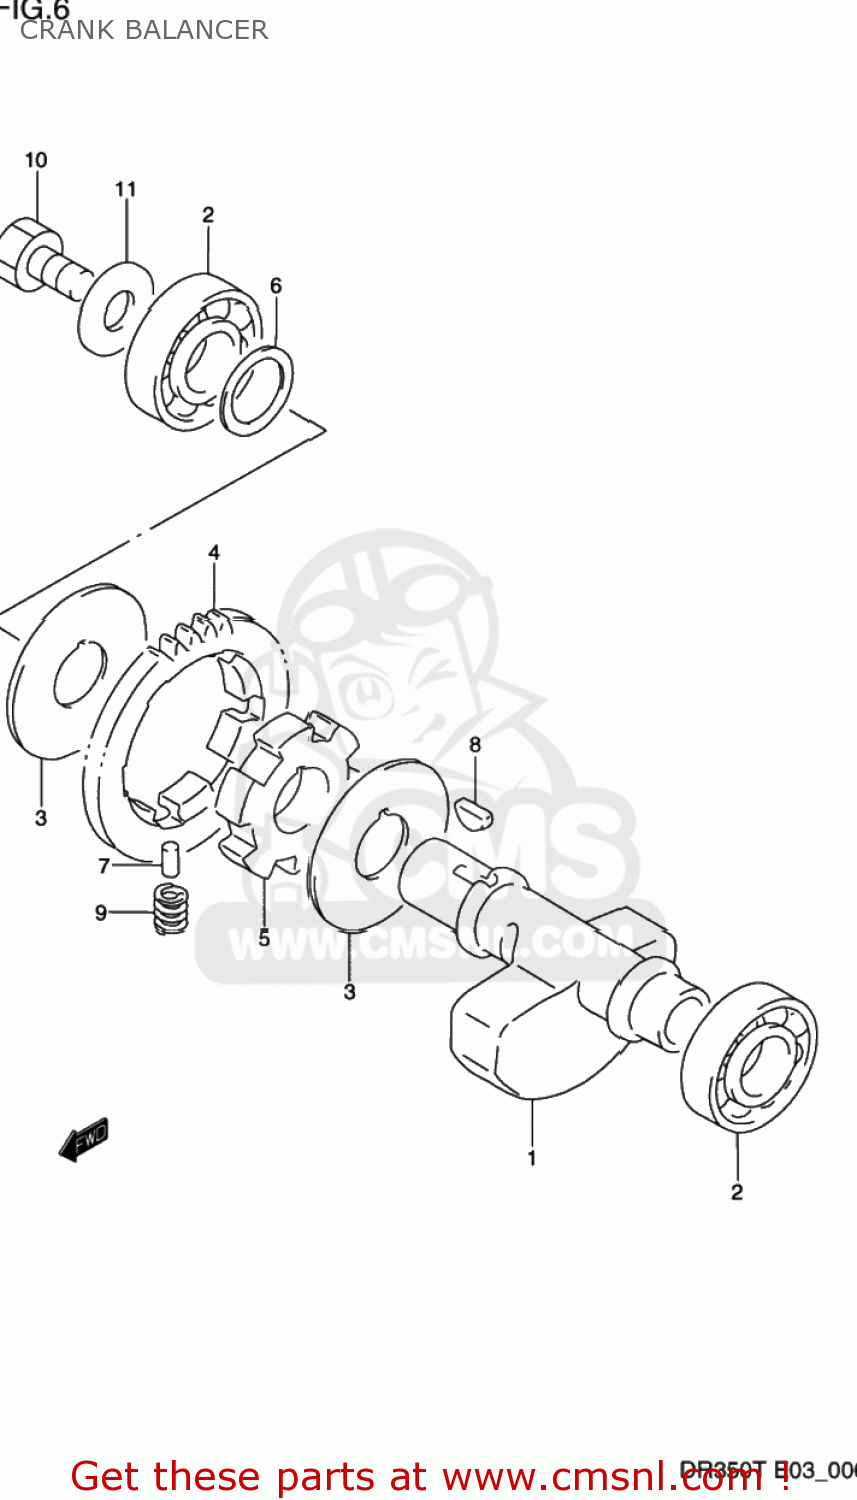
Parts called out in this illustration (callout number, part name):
1	BALANCER,CRANKSHAFT
2	BEARING(20X47X14)
3	WASHER
4	GEAR,CRANK BALANCER
5	RACE,CRANK BALANCER DRIVEN GEAR
6	THRUST WASHER
7	PIN(4.5X9.5)
8	KEY
9	SPRING
10	BOLT
11	WASHER
